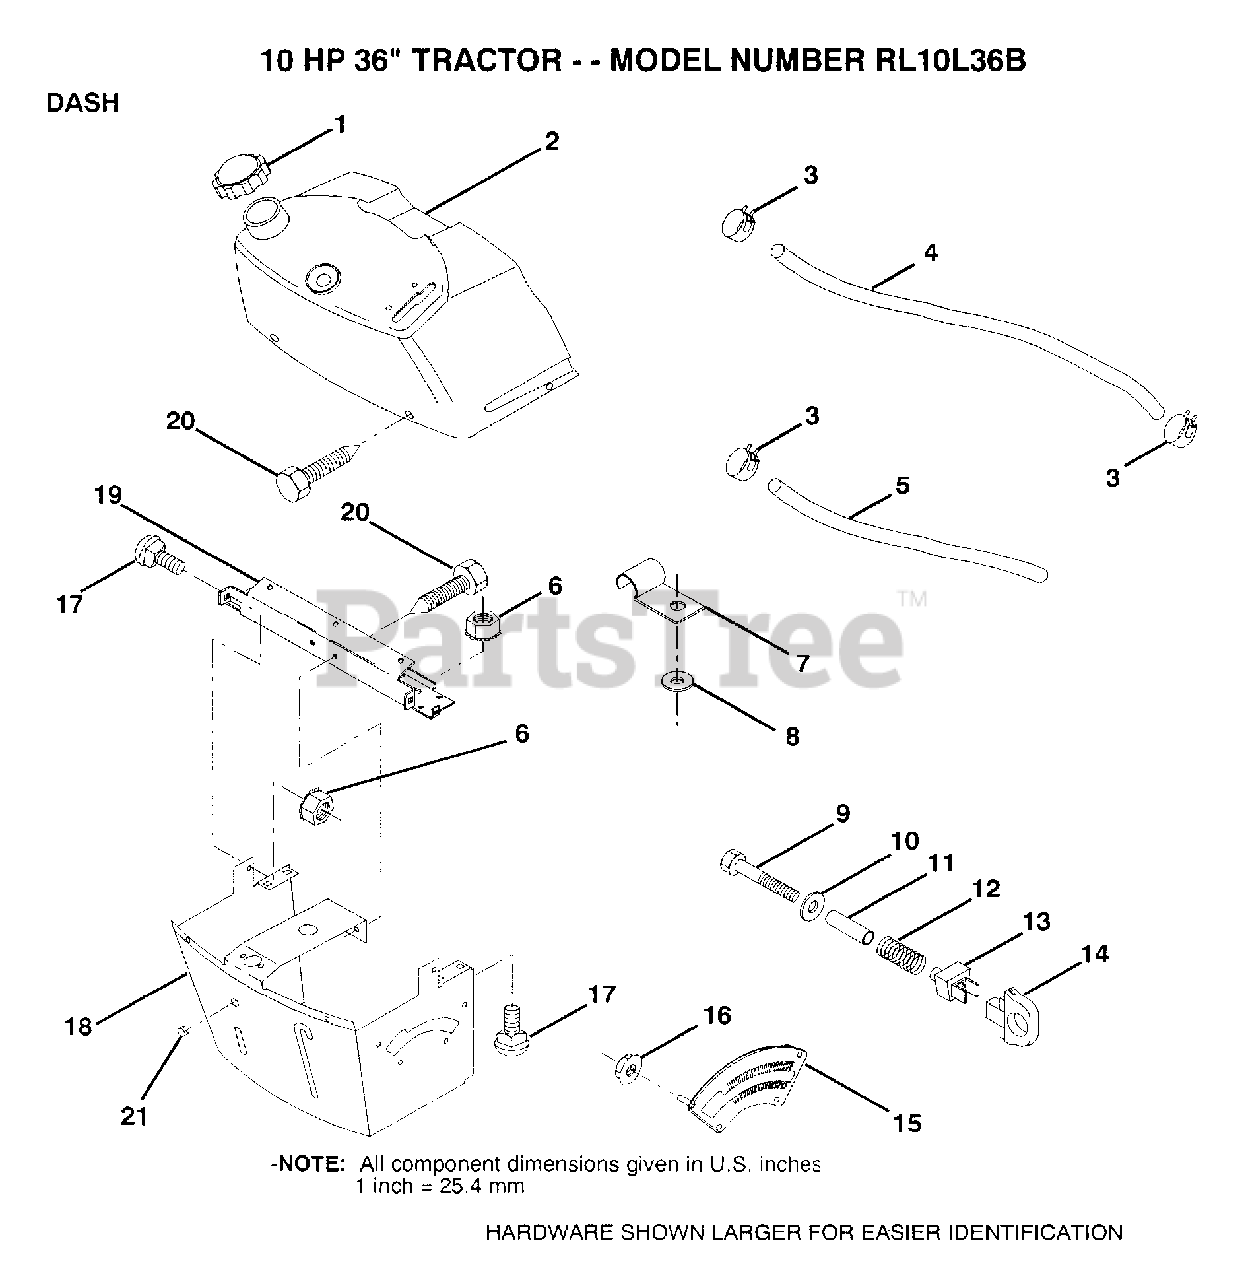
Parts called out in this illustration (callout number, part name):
1	CAP.FUEL.N/VENT
2	TANK.ASM.DASH.LR
3	HOSE CLAMP
5	FUEL LINE T
6	NUT
7	CLIP T
8	WASHER PM
9	BOLT
11	SPACER SPLIT
12	SPRING M
13	"KNOB,HGT RETAINER"
14	KNOB
15	ADJUSTER QUAD
16	NUT
17	BOLT
18	SUPT ASSY DASH
19	CROSS BRACE
20	SCREW.1/4-20X1/2
21	PLUG DOME
